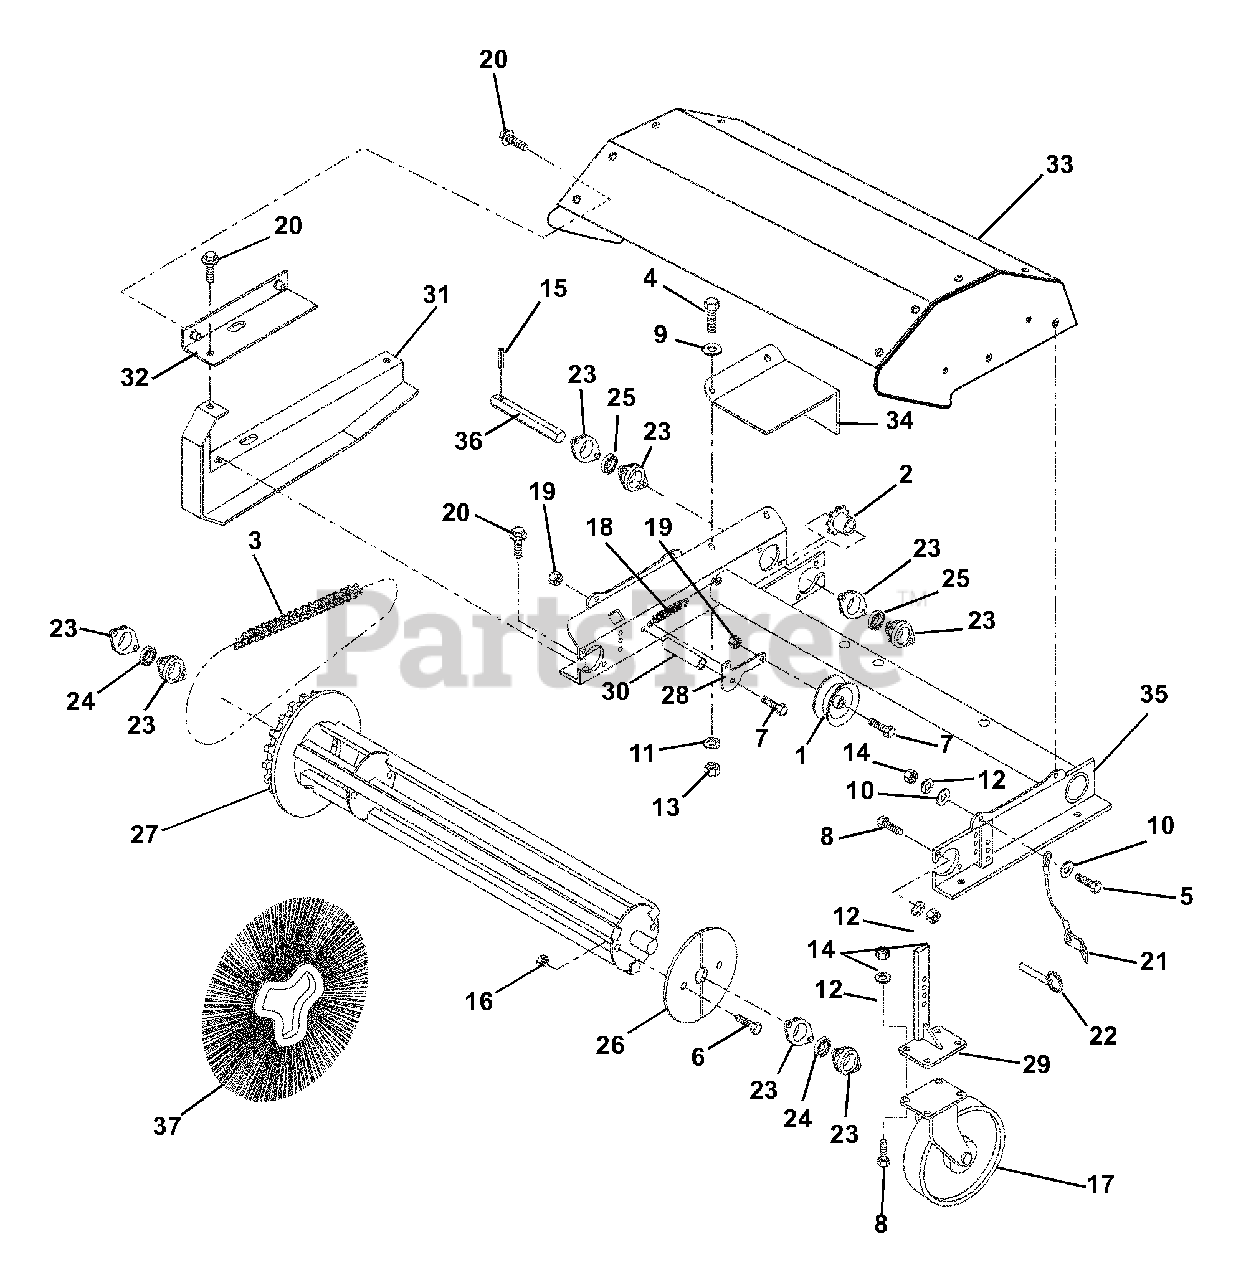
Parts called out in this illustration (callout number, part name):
1	Chain Tightener
2	Sprocket
3	Chain, Assembly #40 x 106
4	Bolt, Hex .25-20 x .75 Grade 5
5	Bolt, Hex .31-18 x 1.00 Grade 5
6	Bolt, Hex .31-18 x 2.25 Grade 5
7	Bolt, Hex .38-16 x 1.50 Grade 5
8	Bolt, Hex .31-18 x .75 Grade 5
9	Washer, Flat Steel .28 x .62 x .065
10	Washer, Flat Steel .31 x .73 x .065
11	Washer, Lock .25 x .062 Regular
12	Washer, Lock .31 x .078 Regular
13	Nut, Hex .25-20
14	Nut, Hex .31-18
15	Pin, Spring Lok .19 x 1.25
16	Nut, Lok Stamped .31-18
17	Wheel, 5 inch Diameter
18	Spring, Tension .50 x 3.00
19	Nut, Locking Center .38-16
20	Screw, Gear 10.9 M6 x 1-20
21	Lanyard .06 Cable 1.25 x 6
22	Pin, Hitch .38 x 2
23	Flange, Spherical 2 inch
24	Bearing 1.00 Bore, Spherical
25	Bearing, Ball .84 Hex x 52 MM x 1.07
26	Retainer Plate
27	Weldment, Core
28	Arm, Idler
29	Weldment, Caster Leg
30	Bushing .62 x 12 Gauge x .75
31	Shield, Chain
32	Shield Chain Top
33	Weldment, Faceted Hood
34	Shield, Input
35	Weldment, Broom Frame
36	Shaft, Hex 20.5 with Hole
37	Set, 24 Section
